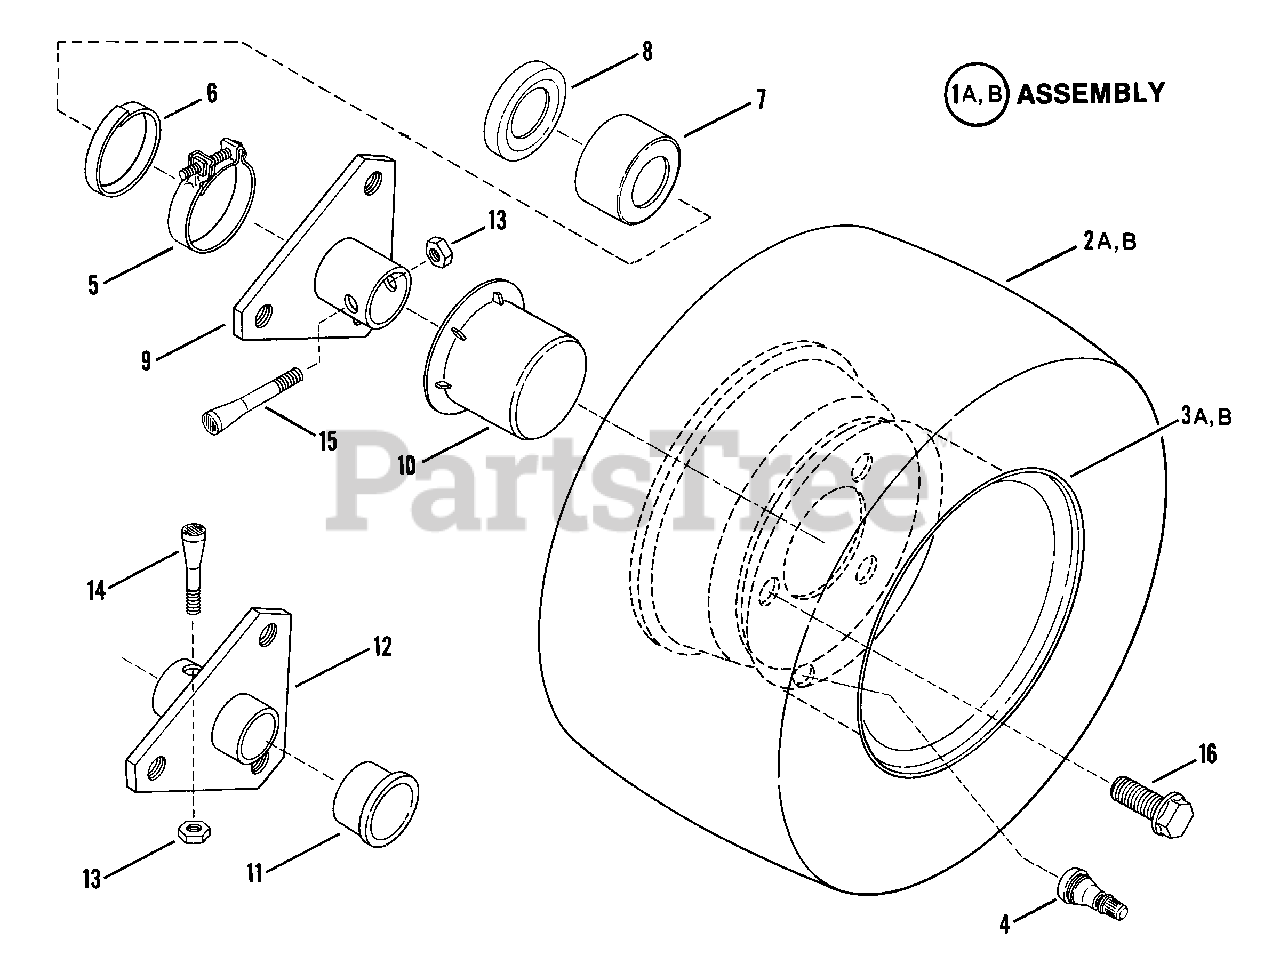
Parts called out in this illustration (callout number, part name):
1A	ASSEMBLY, Rear Tire & Rim
1B	ASSEMBLY, Rear Tire & Rim
2A	TIRE, 16 x 4.80 - 8
2B	TIRE, Wide, 16/6.50x8
3A	RIM, Std., (For 4.80/4.00x8 Tire)
3B	RIM, Wide (For 16/6.50x8 Tire)
4	VALVE, Air (Snap-in)
5	CLAMP
6	RING, Clamp
7	CAP, Seal, Right Hand
8	SEAL, Oil
9	HUB, Rear Wheel, Right Hand
10	HUB-CAP
11	CAP, Seal L.H. 3/4"
12	HUB, Rear Wheel, Left Hand
13	NUT, 5/16-24 Lock
14	BOLT, Tapered, Left Hand
15	BOLT, Tapered, Right Hand
16	BOLT, Lug, (1/2-20x3/4 HHCS)
